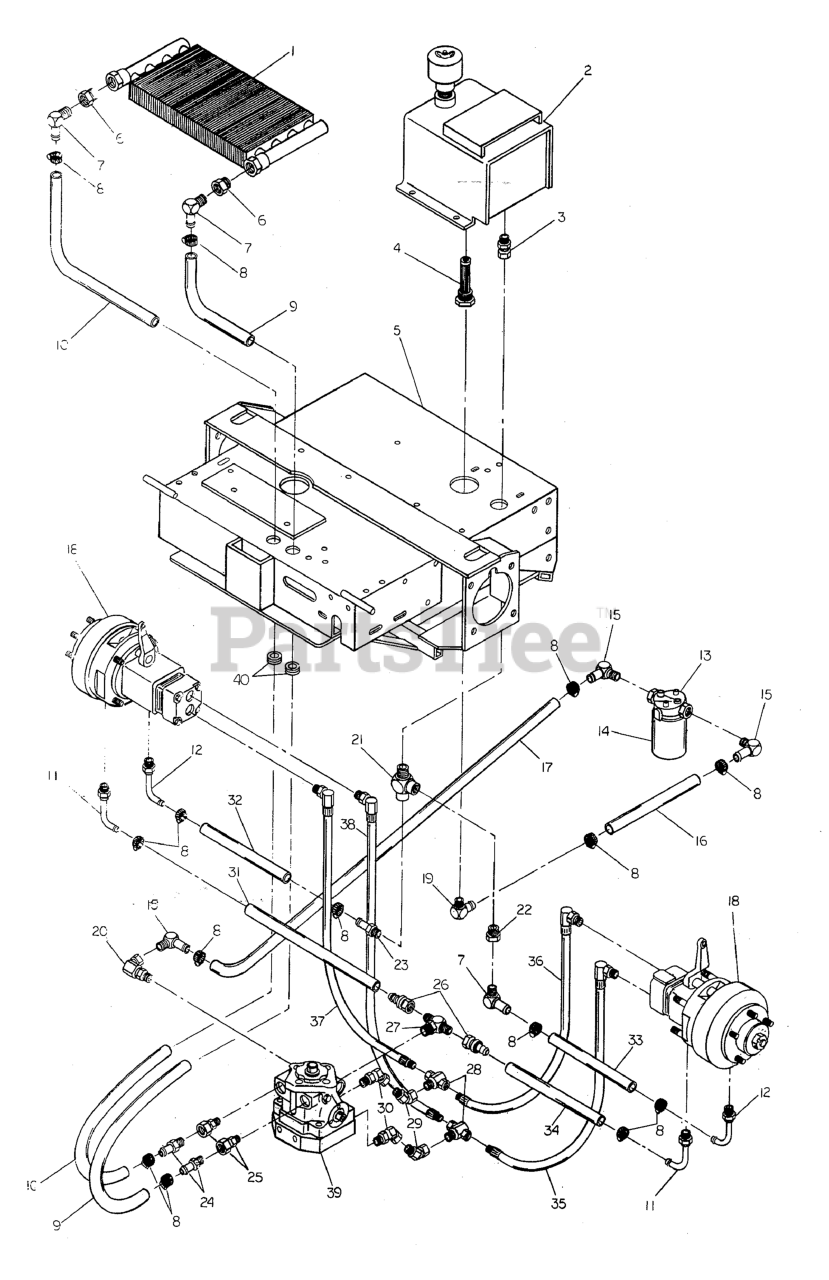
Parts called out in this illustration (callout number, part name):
1	OIL COOLER
2	Hydro Tank
3	FITTING, Straight Swivel
4	STRAINER
5	Engine Deck
6	FITTING, Reducer
7	FITTING, NPT - Hose, 90 Deg.
8	CLAMP, #6 Hose
9	HOSE, 1/2" PUSH-ON, 4.5"
10	1/2" Hose 41" Long
11	105 Degree Fitting
12	90 Degree Fitting
13	FILTER HEAD
14	FILTER, HYDRAULIC, SERVICE PART (PKG)
15	FITTING, 1/2" NPT, 90 Deg.
16	5/8" Hose 22-3/4" Long
17	5/8" Hose 9-3/4" Long
18	Wheel Motor
19	FITTING, 1/2" NPT, 90 Deg.
20	FITTING, O-Ring, 90 Deg.
21	FITTING, Tee
22	FITTING, Reducer
23	Straight Fitting
24	FITTING, 3/8NPT-1/2" Hose, Straight
25	FITTING, O-Ring - NPT, Swivel
26	Swivel - Hose Barb Fitting
27	T- Swivel Fitting
28	FITTING, Tee
29	FITTING, 1/2 NPT, 45 Deg. Swivel
30	FITTING, O-Ring - NPT, 45 Deg.
31	1/2" Hose 26-1/2" Long
32	1/2" Hose 17" Long
33	1/2" Hose 15-1/4" Long
34	1/2" Hose Assembly
35	HOSE ASSEMBLY, 13"
36	HOSE ASSEMBLY, 15"
37	HOSE ASSEMBLY, 19"
38	HOSE ASSEMBLY, 17"
39	HYDRAULIC PUMP
40	GROMMET, 7/8"
